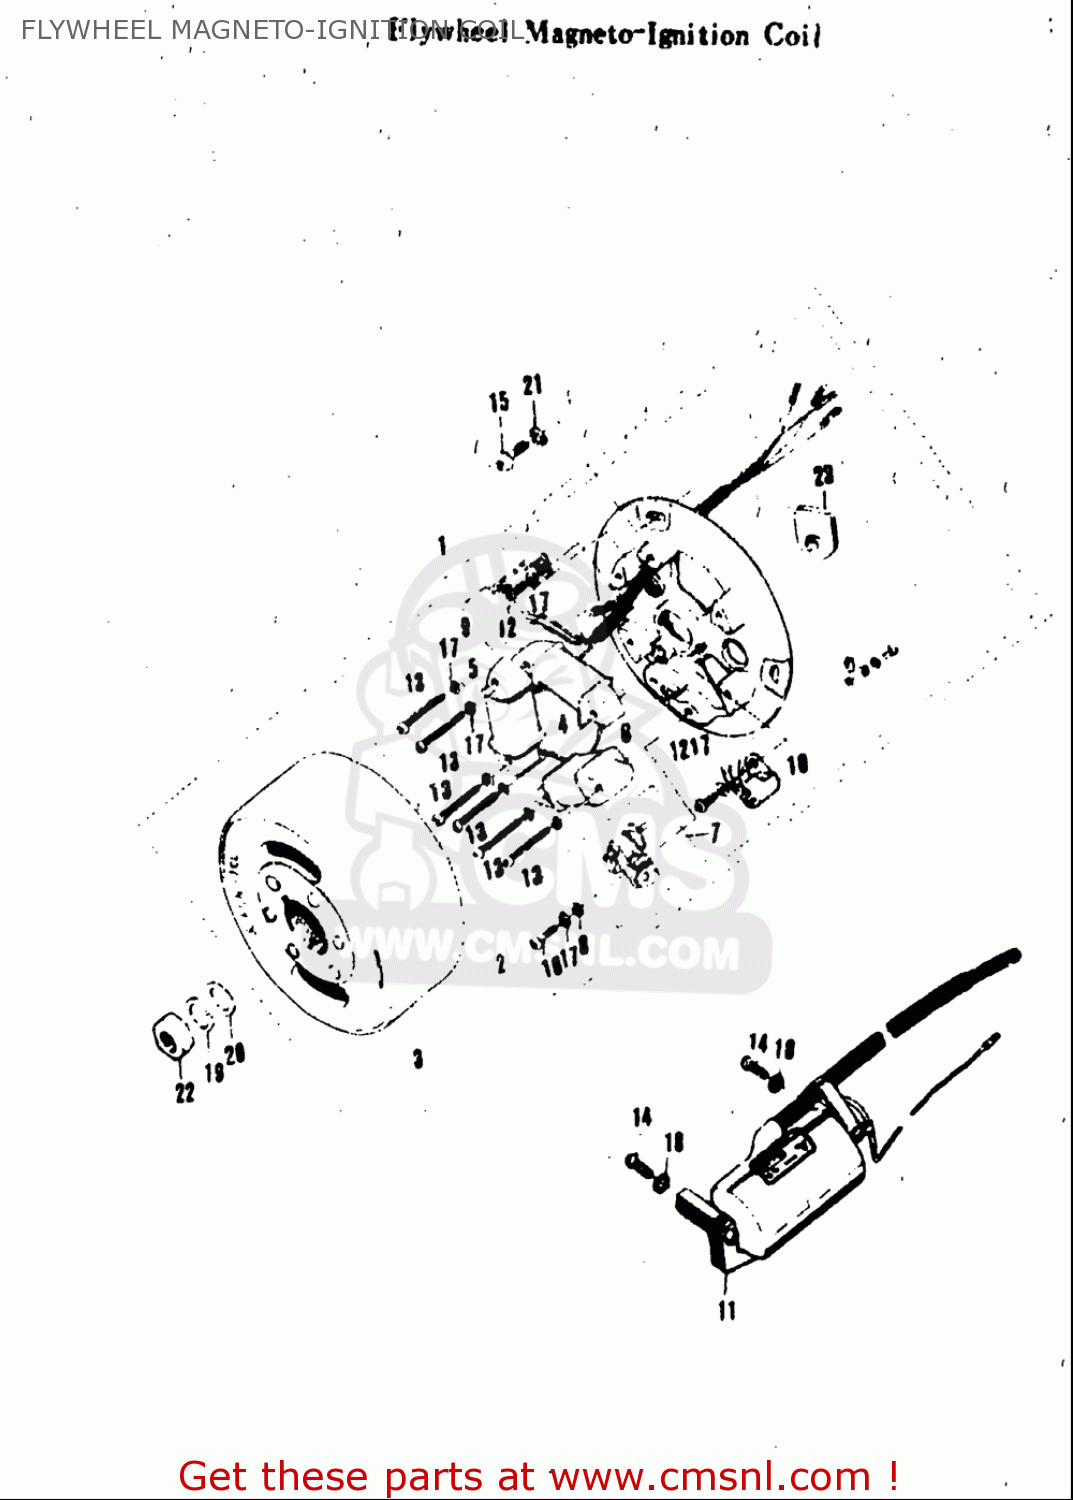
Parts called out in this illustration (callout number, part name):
10	CONDENSER
15	SCREW
16	SCREW
17	WASHER,LOCK
18	WASHER,LOCK
19	WASHER,LOCK
20	WASHER
21	WASHER
22	NUT
